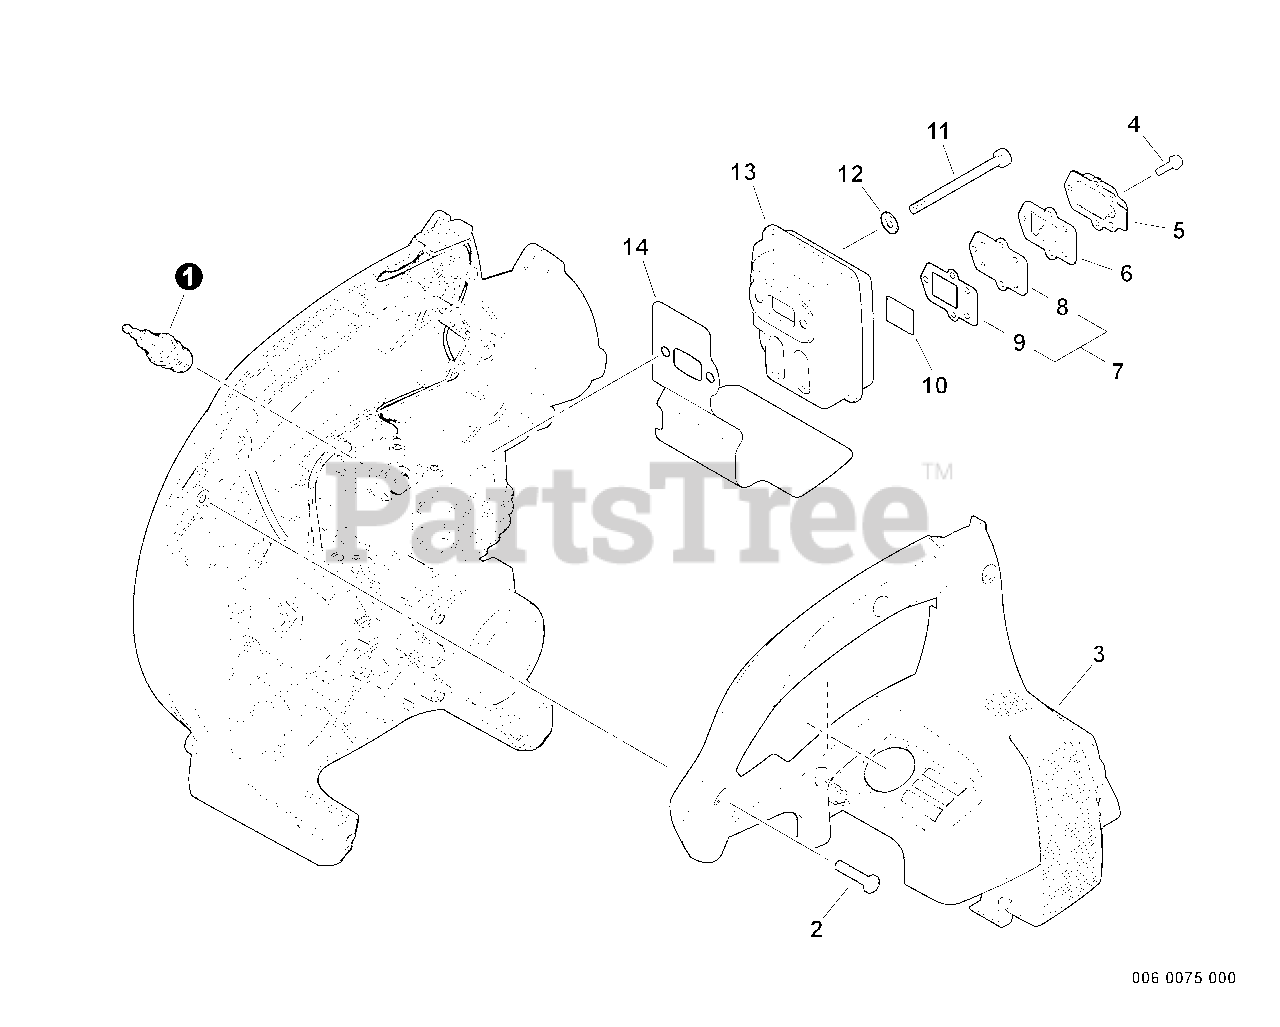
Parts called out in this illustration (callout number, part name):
1	SPARK PLUG - BPM8Y
1	SPARK PLUG - BPMR8Y
2	BOLT, TORX 5×20
3	COVER, ENGINE
4	BOLT, TORX 4×8
5	OUTLET, EXHAUST
6	GUIDE, EXHAUST
7	GASKET KIT, EXHAUST
8	GUIDE, EXHAUST
9	GASKET, EXHAUST
10	SCREEN, SPARK ARRESTER
12	WASHER 5.5×12×0.8
13	MUFFLER
14	HEAT SHIELD, EXHAUST
